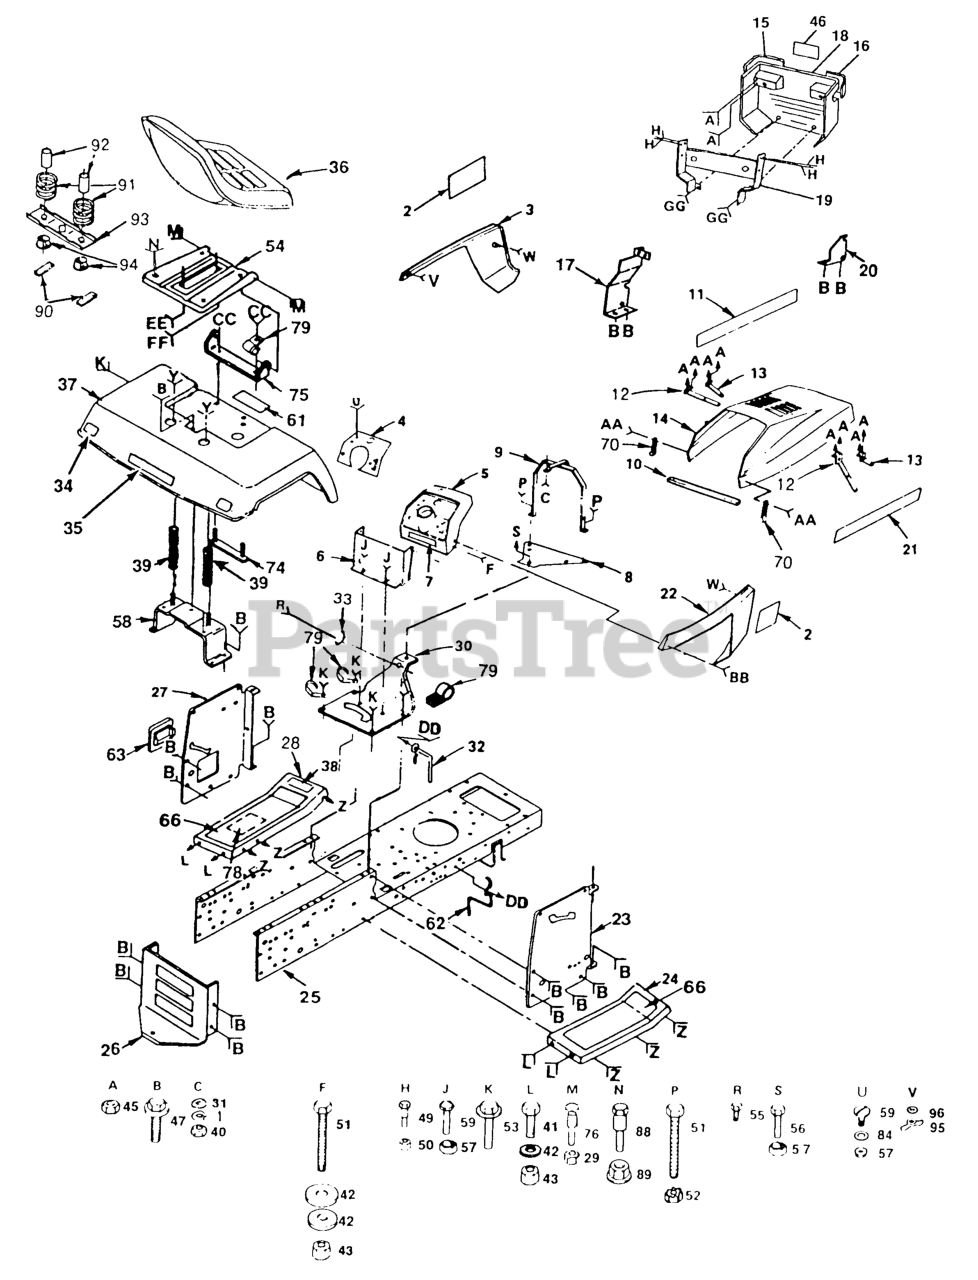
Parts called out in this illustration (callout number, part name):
1	LOCKWASHER
2	DECAL,SIDE PANEL
3	PANEL,SIDE LH
4	PLATE DASH
5	DASHBOARD
6	DASH ASSY LT NLA
8	PLATE SUPPORT T NLA
9	SUPPORT ASSY LT NLA
10	FOAM-STRIP LT
11	DECAL,HOOD LH NLA
12	STRAP ASSY LT
13	STRAP ASSY LT
14	HOOD
15	LENS LH
16	LENS RH
18	GRILL
19	SUPT, ASS'Y GRILL
20	SUPPORT LH YTH
21	DECAL,HOOD RH
22	PANEL,SIDE RH
23	PANEL DASH RH YT NLA
24	FOOTREST RH
25	CHASSIS ASSY NLA
26	DRAWBAR
27	PANEL LH T NLA
28	FOOTREST LH
29	LOCKNUT
31	WASHER PM
32	BELT GUIDE
33	BUSHING LT
34	REFLECTOR-TAIL YT
35	DECAL,FENDER HUSQ
36	SEAT
39	SPRING COMPRESSION
40	NUT
42	WASHER
45	NUT
46	DECAL,GRILL HUSKY
47	SCREW
49	BOLT T
50	NUT.CROWNLOCK.1/4
53	SCREW LT
55	SCREW LT
56	BOLT.FIN.HEX.5/16-18X3/4
57	NUT
58	BRACKET-FENDER YT
59	Screw-Truss Hd. 5/16-18 x 3/4
62	BELT GUIDE
63	COVER ACCESS
66	PAD FOOTREST T
70	LATCH.HOOD.
74	STRAP-FENDER YT
75	BRKT,SEAT PIVOT
76	BOLT, SHOULDER LT
79	CLIP T
84	WASHER
88	Bolt Carriage 1/4 - 20 x 1-1/4
89	NUT T
90	STRIP FORM
92	SPACER SPLIT
93	BRKT SWITCH
95	NUT.WING.LCK.NYL.NOTCH.1/4-20
96	LOCKWASHER GT
